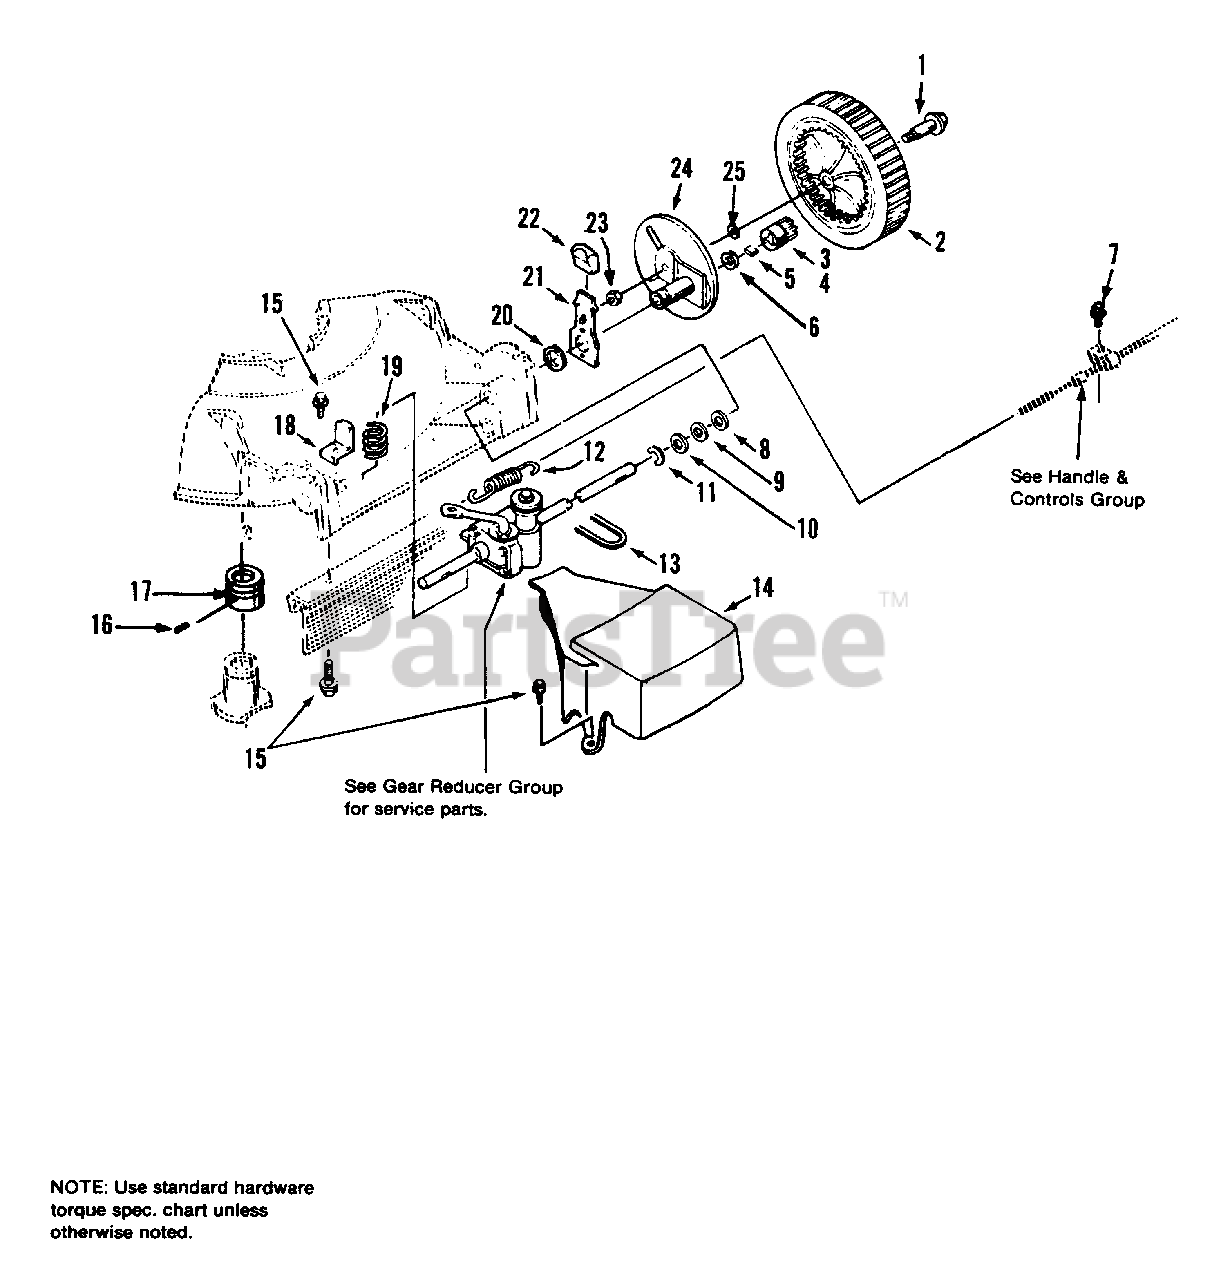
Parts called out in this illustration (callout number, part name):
1	BOLT, Axle, 3/8-16
2	WHEEL & TIRE
3	PINION, R.H.
4	PINION, L.H.
5	PAWL, Pinion
7	SCREW, Thread Rolling
9	WASHER, Shim
11	RING, Eaton
12	SPRING, Extension
13	BELT, Drive
14	COVER, Drive
15	SCREW, Hex Hd., 1/4-20 x 3/4
16	SCREW, Set
17	PULLEY, Drive
21	SPRING, Index
23	NUT, 3/8-16
24	SUPPORT, Drive Wheel
